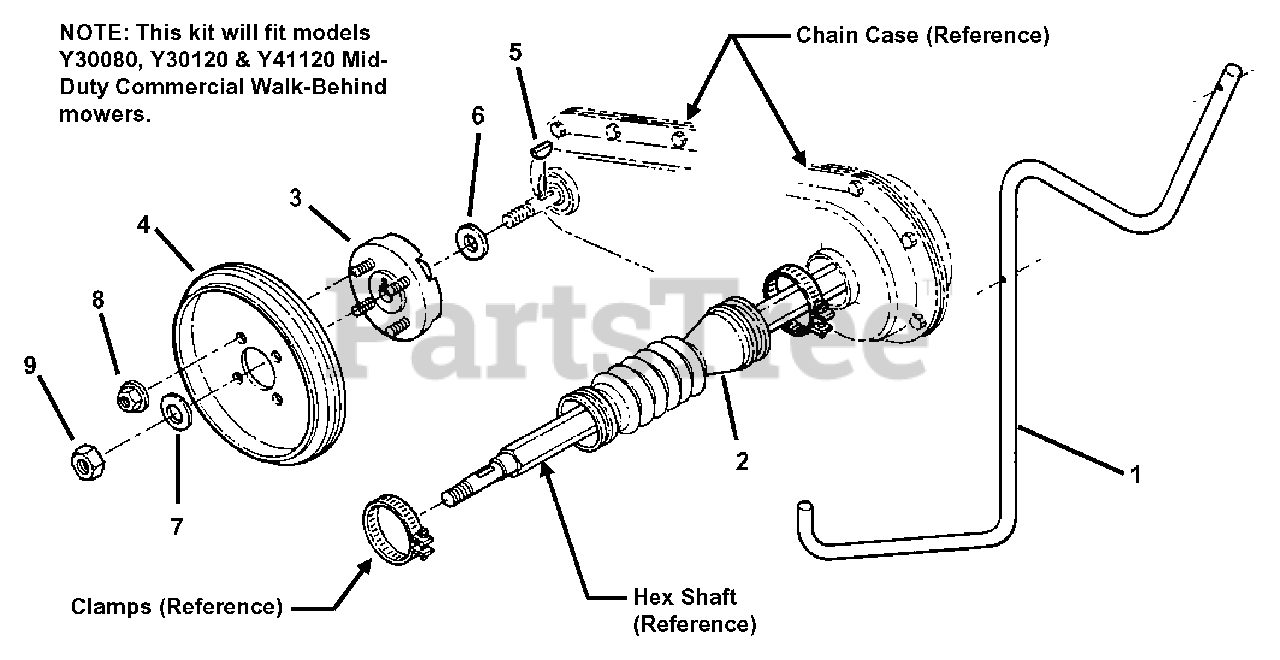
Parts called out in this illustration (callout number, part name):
1	SHIFT LEVER, Lower
2	COVER, Shaft
3	HUB ASSEMBLY
4	DRIVEN DISC
5	KEY, 3/32 x 1/2" Woodruff (#304)
6	WASHER, 5/16" Flat
7	WASHER, 3/8" Belleville
8	NUT, 1/4-20 Hex Flange Lock
9	NUT, 3/8-24 Hex, Grade C
